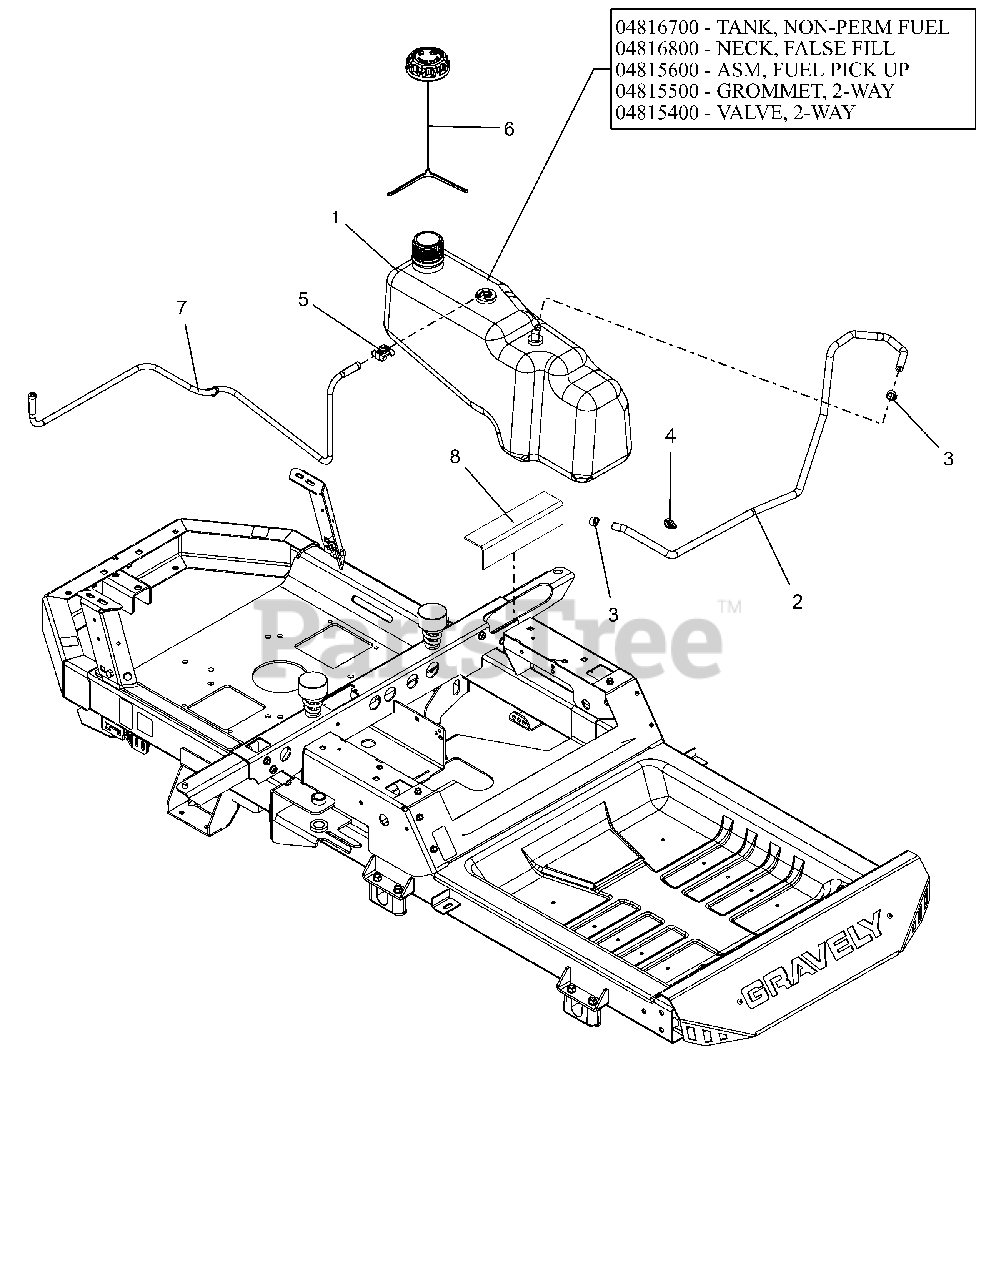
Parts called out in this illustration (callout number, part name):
1	ASM,TANK NON-PERM FUEL
1	TANK, ZOOM/ZT NON-PERM, FUEL
1	NECK, FALSE FILL ZOOM/ZT
1	ASM, FUEL PICK-UP ZOOM/ZT 2015
1	GROMMET, 2-WAY
1	VALVE, 2-WAY
2	HOSE, .25 LOW-PERM BULK GAS
3	CLAMP, FUEL LINE
4	ROUTING CLIP (1/2" ID)
5	CLIP, T, .38-.50
6	CAP, FUEL VENT-IN 2.25" RATCH.
7	LINE, FUEL VENT KOHLER SMCHOKE
8	PAD, RUBBER-TANK
